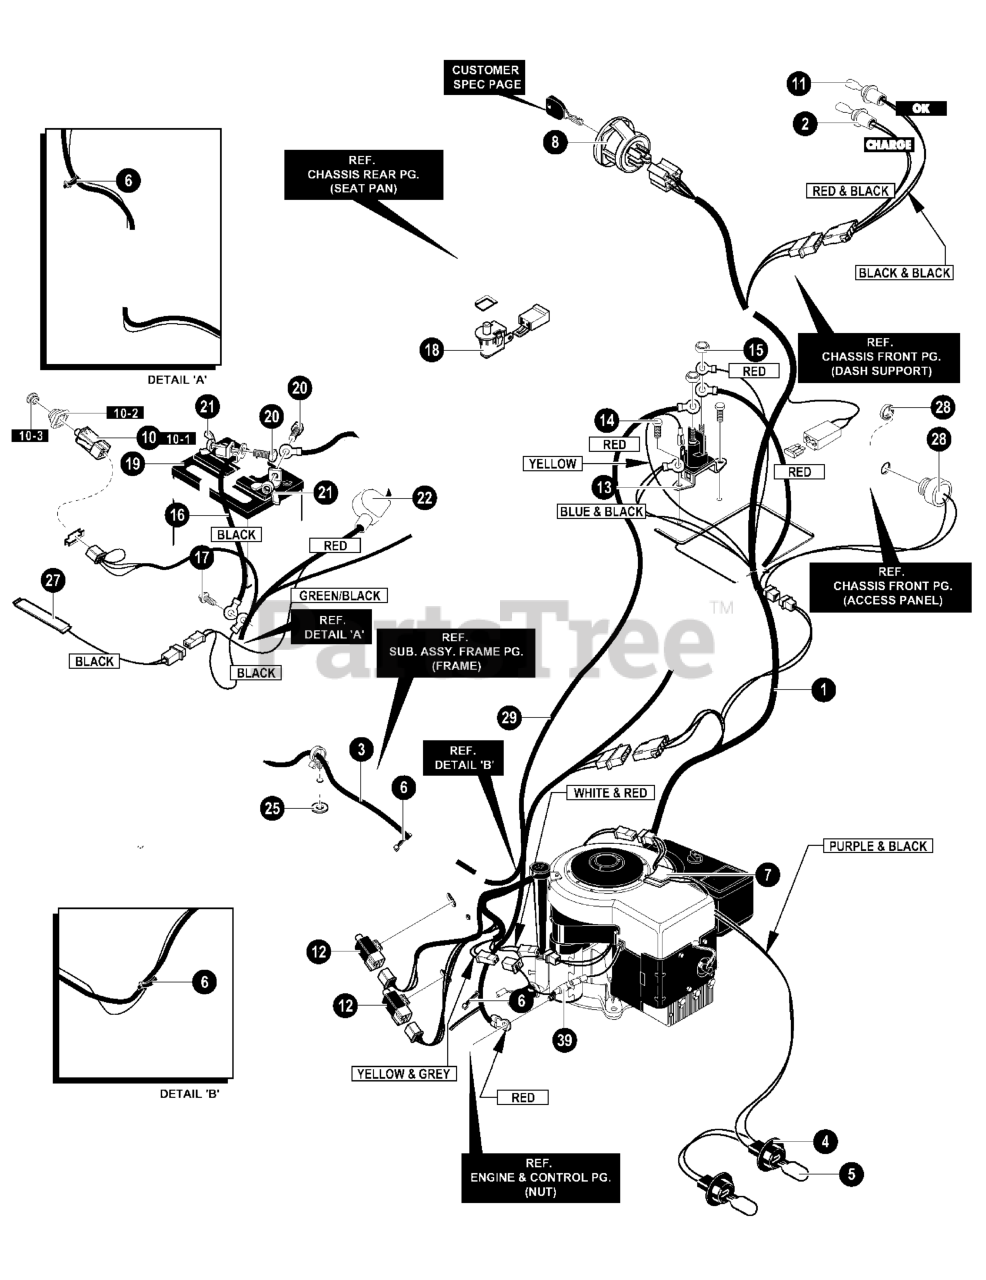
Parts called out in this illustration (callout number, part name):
1	WIRE HARNESS
2	INDICATOR HARNESS
3	REAR HARNESS
4	WIRE HARNESS FOR HEADLIGHTS
5	BULB, HEADLAMP
6	TIE, CABLE BLACK NYLON 5.62L
7	WIRE CLIP, ADHESIVE
8	SWITCH, IGNITION
10	ASSY, SWITCH DOUBLE POLE DELTA
10-1	SWITCH, DOUBLE
10-2	BOOT, SWITCH
10-3	SWITCH CAP
11	BULB, INDICATOR
12	SWITCH LIMIT
13	SOLENOID
14	SCREW, 1/4X.50
15	NUT, 1/4-20 HEXNYL
16	WIRE, GROUND
17	SCREW,1/4X.50
18	SWITCH, SEAT
19	BATTERY 5 PLATE MAINT FREE
20	BOLT,1/4-20X.63
21	NUT, WING 1/4-20
22	BOOT, BATTERY
25	WASHER, FLAT .250X56X.0478
27	TAPE SWITCH
28	BUZZER, FOR BAG FULL
29	WIRE, LEAD SOLENOID TO STARTER
39	HARNESS ADAPTER
